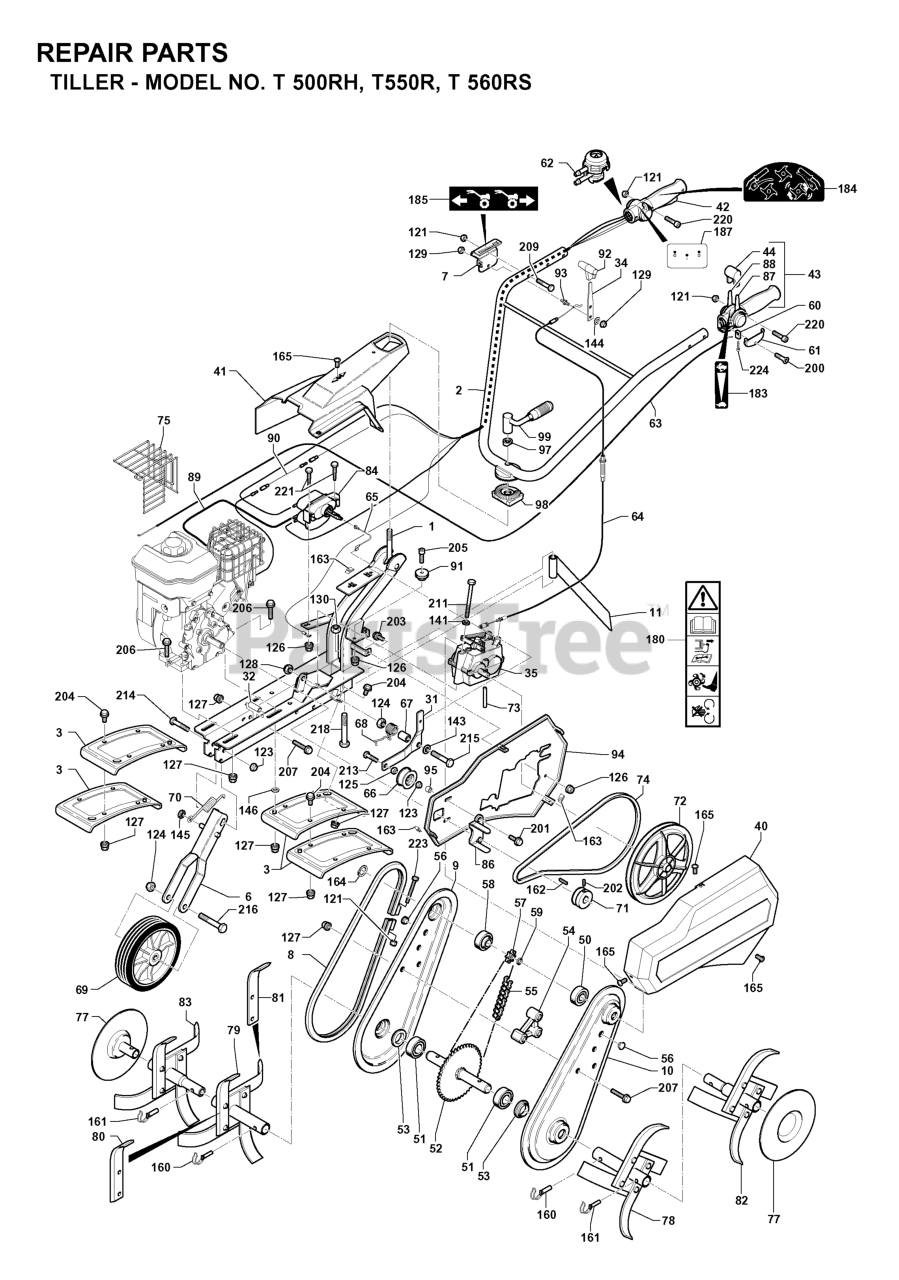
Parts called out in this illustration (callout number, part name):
31	ARM
55	DRIVE CHAIN
69	WHEEL
121	Blocking nut M 6 Z
164	RETAINING RING
